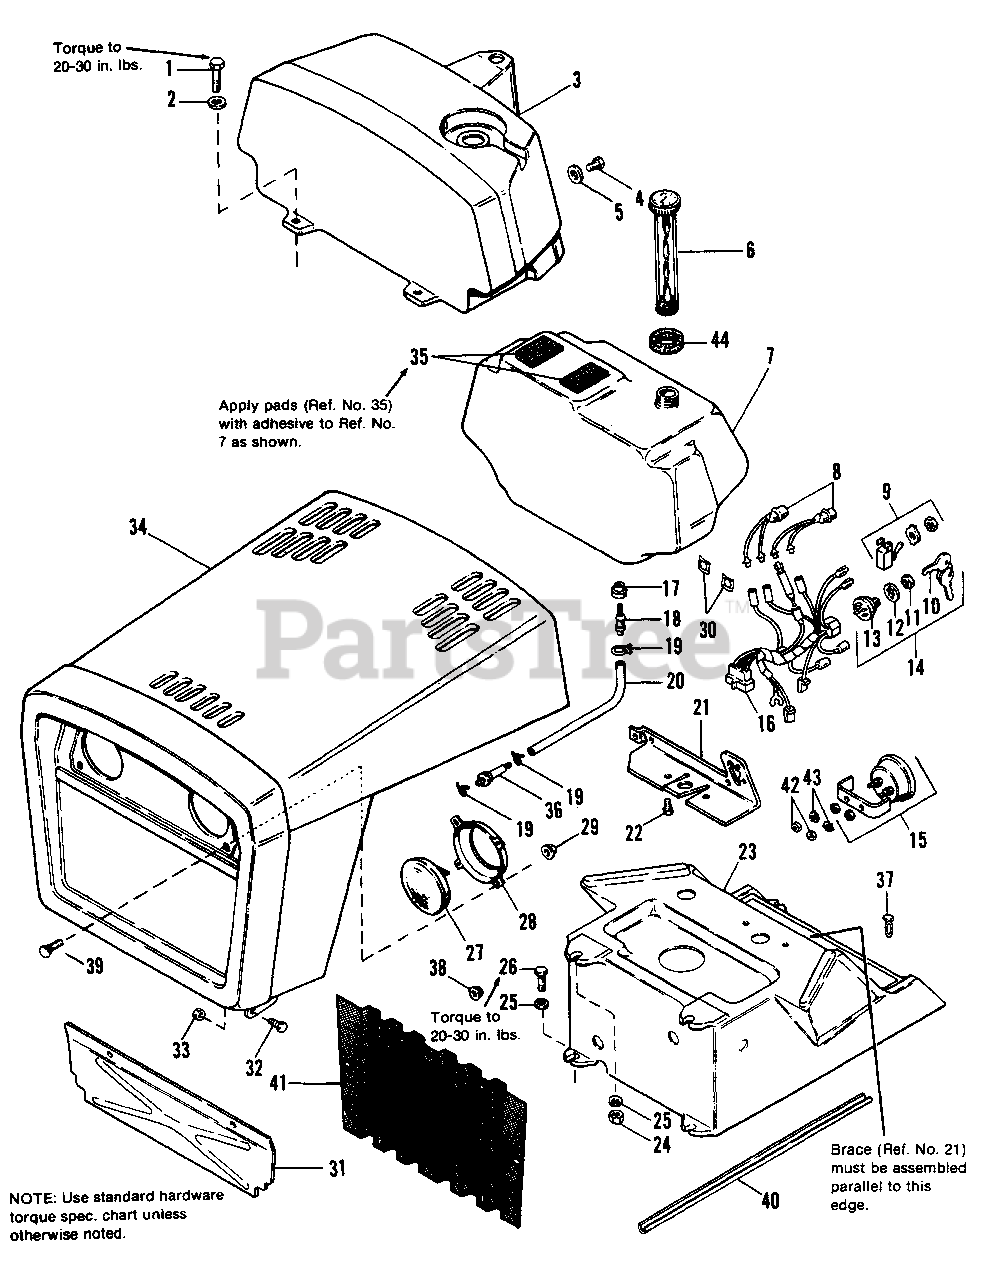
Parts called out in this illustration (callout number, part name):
1	CAPSCREW, Hex, 1/4-20 x 1-1/4
2	WASHER, Plain, 1/4
3	DASHBOARD, Top
4	SCREW, #14 x 3/4
5	WASHER, Plain, 3/16
7	TANK ASSY., Fuel (Incl. Ref. Nos. 19 & 20)
8	LIGHT, Indicator
9	SWITCH, Toggle
11	NUT, Hex, 5/8-32
12	LOCKWASHER, Int., 5/8
14	SWITCH ASSY, Ignition (Incl. Ref. Nos. 10, 11, 12 & 13)
15	AMMETER
16	HARNESS, Upper (6212.5 & 6216 Only)
16	HARNESS, Upper (6211 Only)
21	BRACE, Dash
22	SCREW, Taptite, 1/4-20 x 3/4
23	DASHBOARD, Bottom
24	LOCKNUT, Hex, 1/4-20
25	LOCKWASHER, Dished, 1/4
26	SCREW, Taptite, 1/4-20 x 1
27	LAMP, Sealed Beam
28	BRACKET, Headlight Support
30	NUT, Speed, Push on
31	BAFFLE, Engine, Front (6212.5 & 6216 Only)
32	CAPSCREW, Hex, 3/8-16 x 7/8
33	LOCKNUT, Hex, 3/8-16
34	HOOD & GRILLE ASSY.
36	FILTER, Fuel
37	CLIP, Canoe
38	LOCKNUT, Palnut #10-24
39	BOLT, Carriage
40	EDGING,Lower Dash
41	SCREEN, Grille
42	NUT, Hex, #10-32
43	LOCKWASHER, #10, Ext. Tooth.
44	WASHER, Foam (6212.5, 6216)
